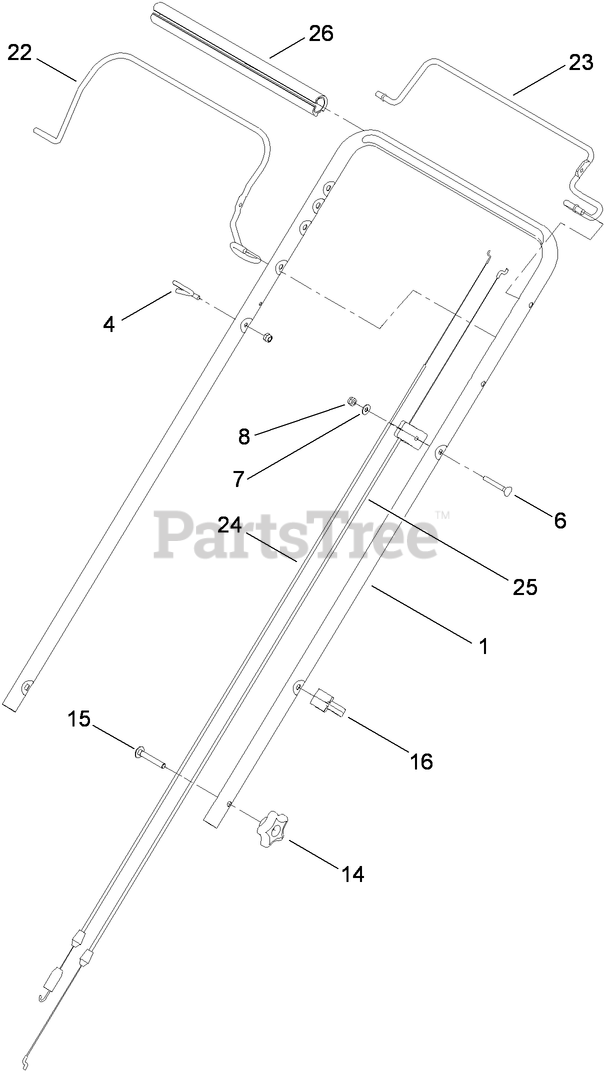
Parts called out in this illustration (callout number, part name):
4	GUIDE-ROPE
6	SCREW-HANDLE
7	WASHER-FLAT
8	NUT-LOCK, NI
14	KNOB-HANDLE
15	BOLT-CARR
16	GUIDE-CABLE
22	BAIL-BRAKE
23	BAIL-TRACTION
24	CABLE-TRACTION
25	CABLE-BRAKE
26	GRIP-HANDLE, COMFORT
